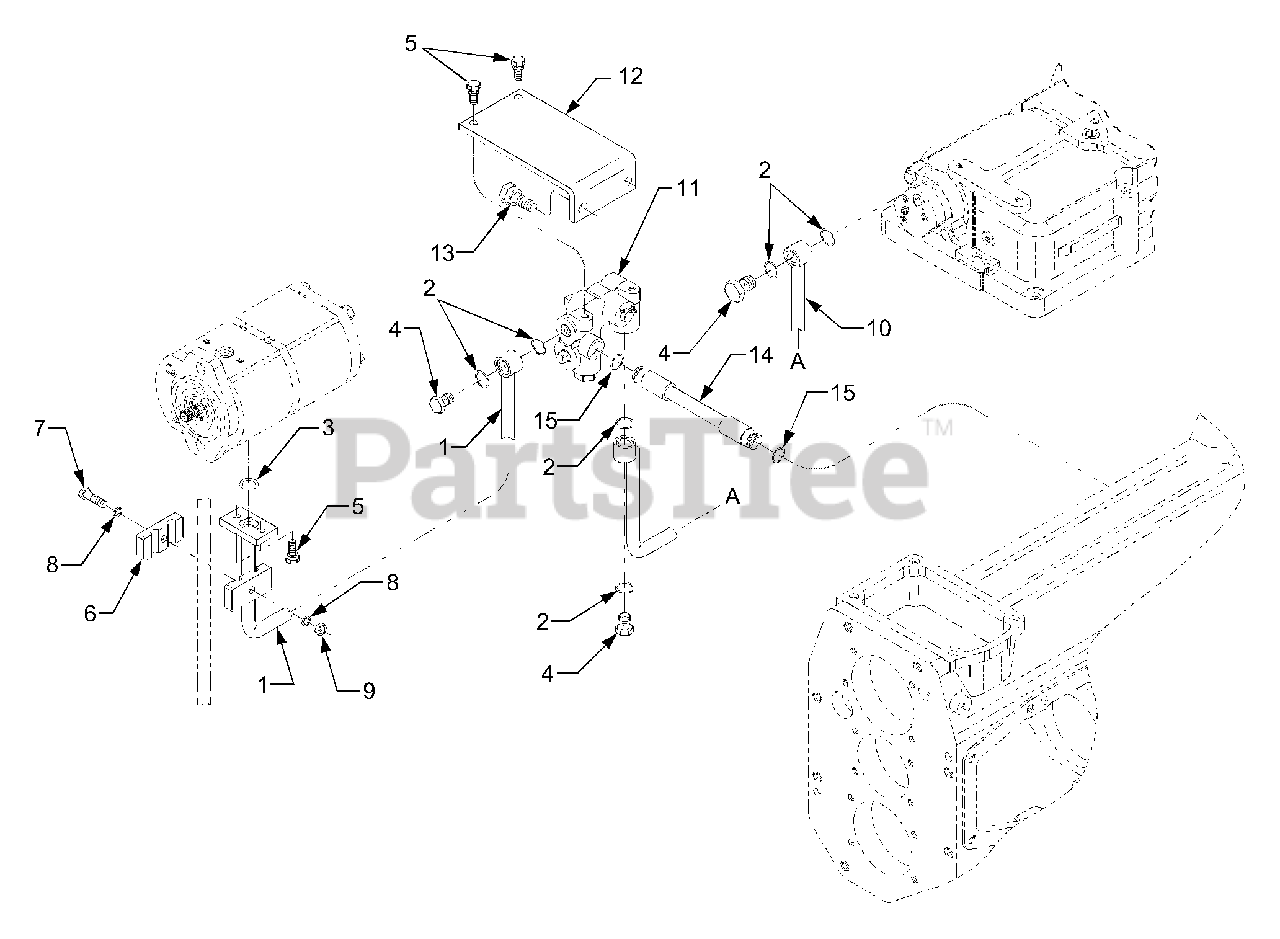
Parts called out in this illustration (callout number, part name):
1	Pipe 1, Hydraulic
6	Clamp 2, Pipe
8	Washer, Plain
10	Pipe 2, Hydraulic
11	Hydraulic Block Ass'y
12	Support, Hydraulic Block
